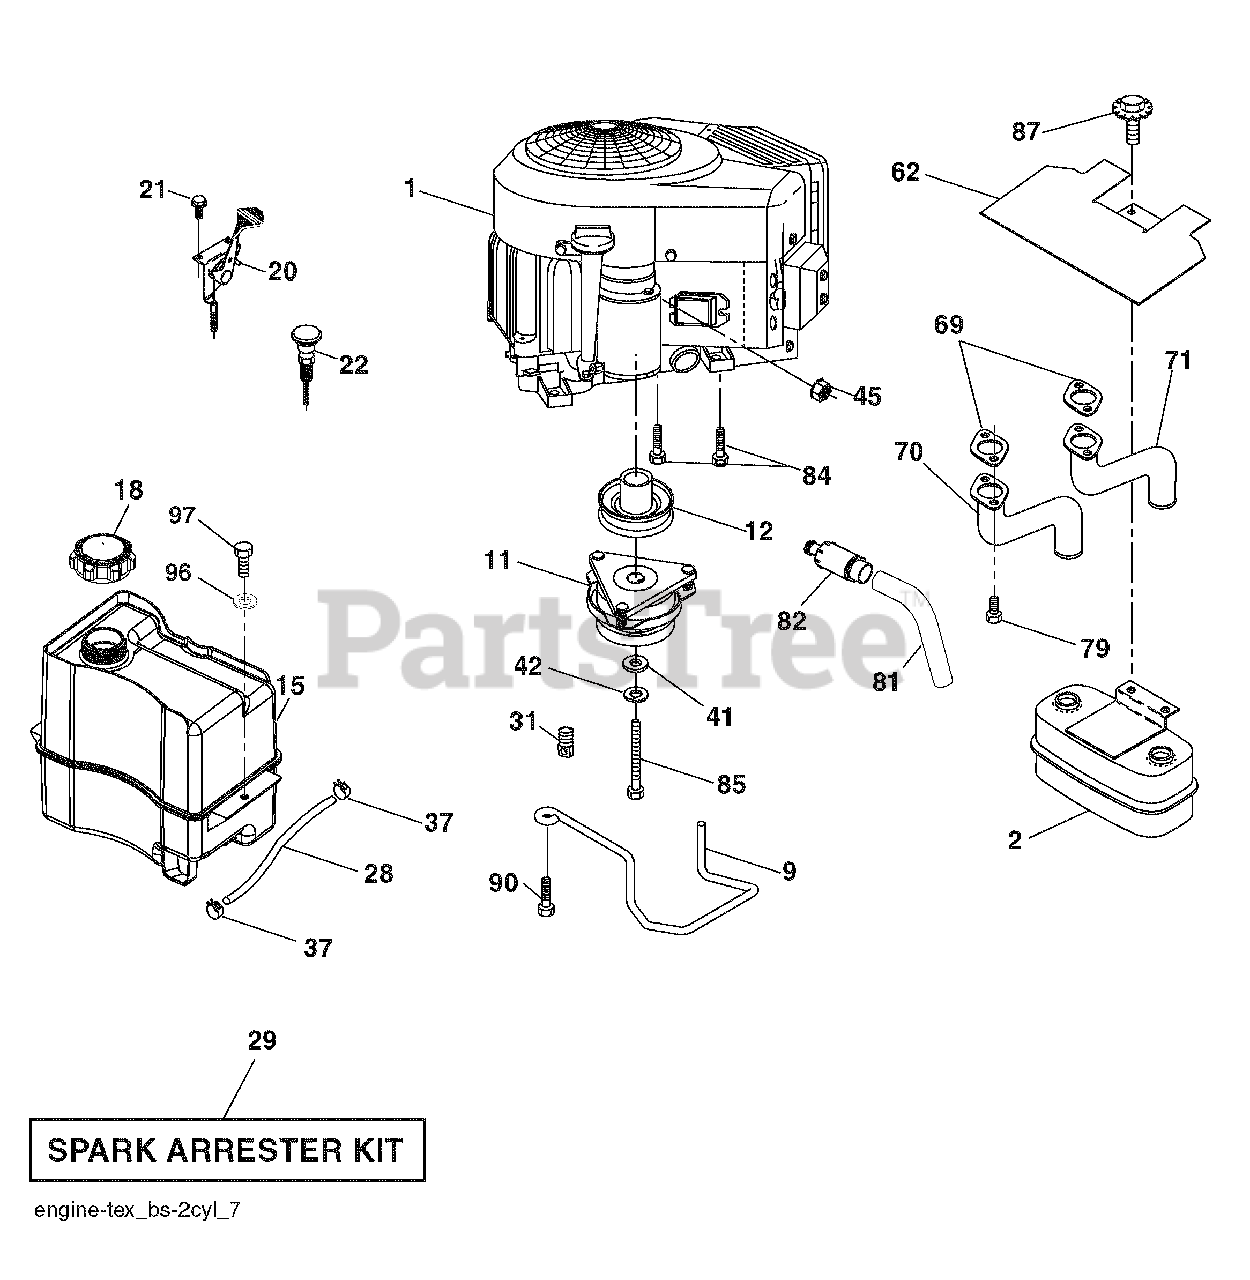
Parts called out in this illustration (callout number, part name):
9	Keeper Belt Engine
11	Clutch Electric
12	Pulley Engine
15	Tank Fuel
18	Cap Asm
20	Control Throttle
21	Screw #10 x .750 BOS Thread
22	Choke Control
28	Fuel Line
29	Spark Arrester Kit
31	Clip Push-in Hinged
37	Clamp Hose
41	Washer 1-1/2 OD x 15/32 ID x .250
42	Washer Lock 7/16
45	Nut Keps Hex 1/4-20 unc
62	Heat Shield
70	Tube Exhaust
71	Exhaust Tube
79	Screw Socket HP 5/16-18 x 1
81	Tube Drain Oil Easy
82	Plug Drain Oil
84	Screw 3/8-16 x 1-1/4
85	Bolt Hex 7/16-20 x 4 x Gr. 5-1.5 Thr
87	Bolt 5/16-18 unc x 3/4 w/Sems
90	Screw 3/8-16 x 1
96	Washer 9/32 x 7/8 x 16 Ga.
97	Screw 1/4-20 x 3/4
